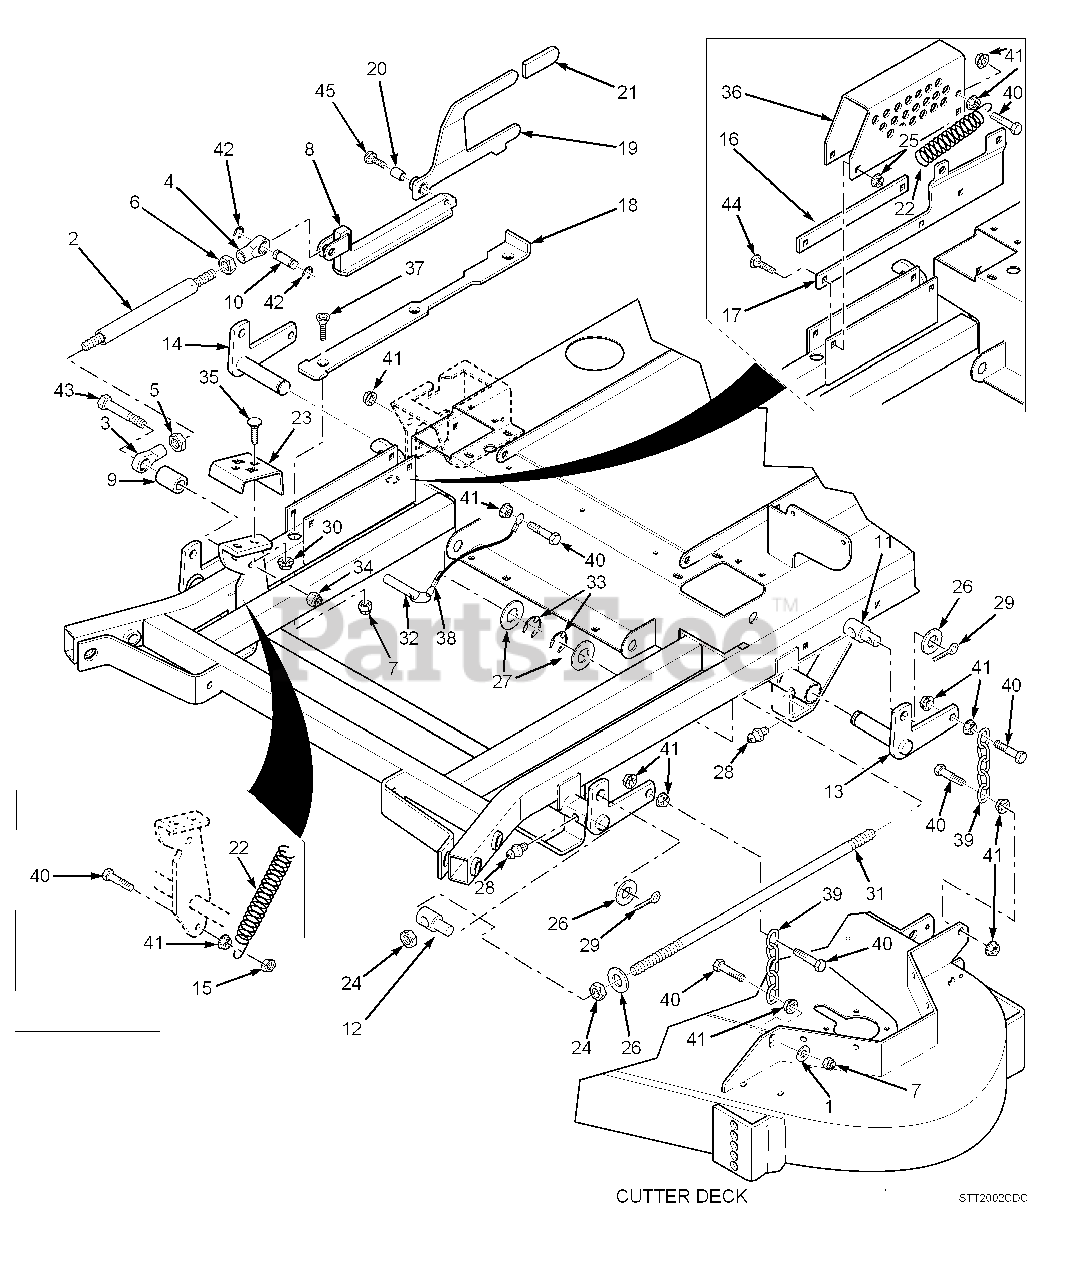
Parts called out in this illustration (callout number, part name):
1	Flatwasher, 3/8"
2	Link, Deck Lift
3	Rod End, Female - 1/2-20 RH
4	Rod End, Female - 1/2-20 LH
5	Nut, Jam 1/2-20 RH
6	Nut, Jam 1/2-20 LH
7	Nut, 3/8-16 Elastic Stop
8	Slide Weldment, Height Adjustment
9	Spacer, Decklift Pedal
10	Pin, Decklift
11	Swivel Joint, LH
12	Swivel Joint, RH
13	Bellcrank Weldment, LH Rear
14	Bellcrank Weldment, RH Rear
15	Locknut, 3/8-16 Center Lock
16	Guide, Short
17	Guide, Long
18	Lockplate, Decklift
19	Deck Latch
20	Bushing, .502 ID.
21	Grip, Deck Latch
22	Spring, Helper
23	Foot Pedal, Height Adjustment
24	Nut, Hex 5/8-11
25	Nut, Hex Serrated Flange 5/16-18
26	Flatwasher, 5/8"
27	Flatwasher, 1"
28	Grease Fitting
29	Cotter Pin, 3/16 x 1"
30	Nut, Hex Elastic Stop 5/16-18
31	Stud, 5/8-11 x 22.0"
32	Ring Pin, 1/2 x 3.30"
33	Ring, Retaining 1" External "E"
34	Nut, Hex Elastic Stop 1/2-13
35	Bolt, Carriage 3/8-16 x 1-1/4"
36	Bracket, Cutting Height Adjustment
37	Screw, Cap 5/16-18 x 3" FHHS
38	Lanyard, Deck Height Pin
39	Chain
40	Bolt, Hex Head 3/8-16 x 1-1/2"
41	Nut, Hex Serrated Flange 3/8-16
42	Ring, Retaining 1/2" External "E"
43	Bolt, Hex Head 1/2-13 x 3"
44	Bolt, Carriage 5/16-18 x 1"
45	Bolt, Shoulder 1/2 x 3/4"
